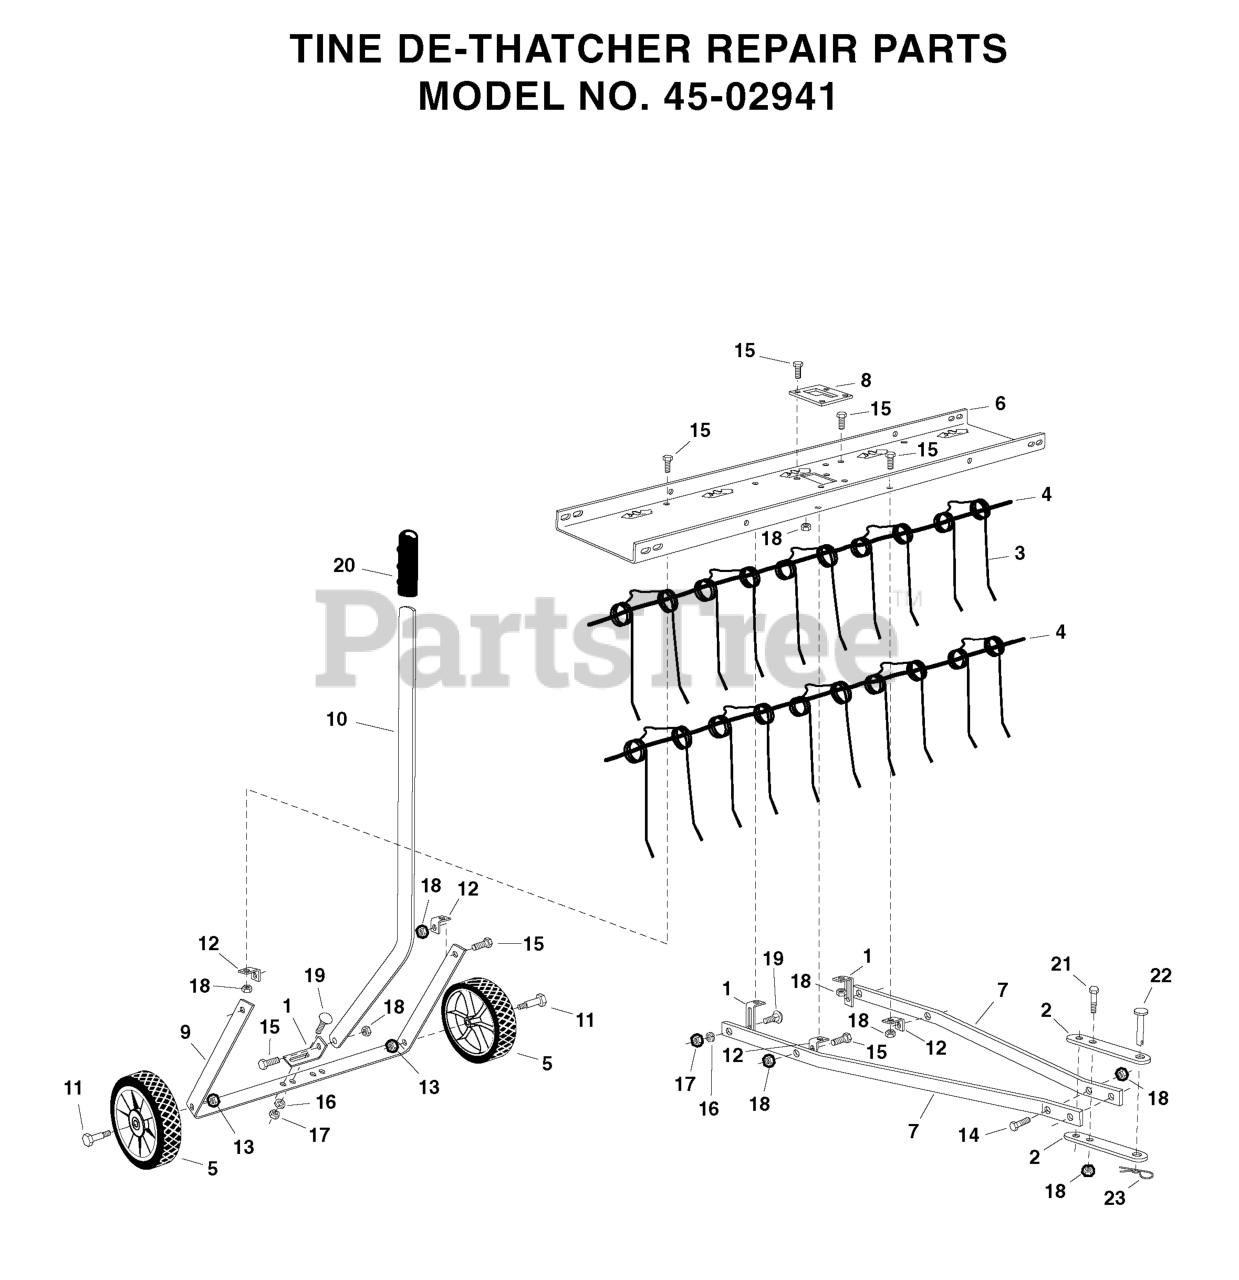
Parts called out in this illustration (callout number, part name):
2	BRACKET THATCHER
3	SPRING TINE
15	BOLT.FIN.HEX.5/16-18X3/4
20	Rubber Grip
21	Bolt Fin Hex 5/16 - 18 Unc x 2 Gr. 2
